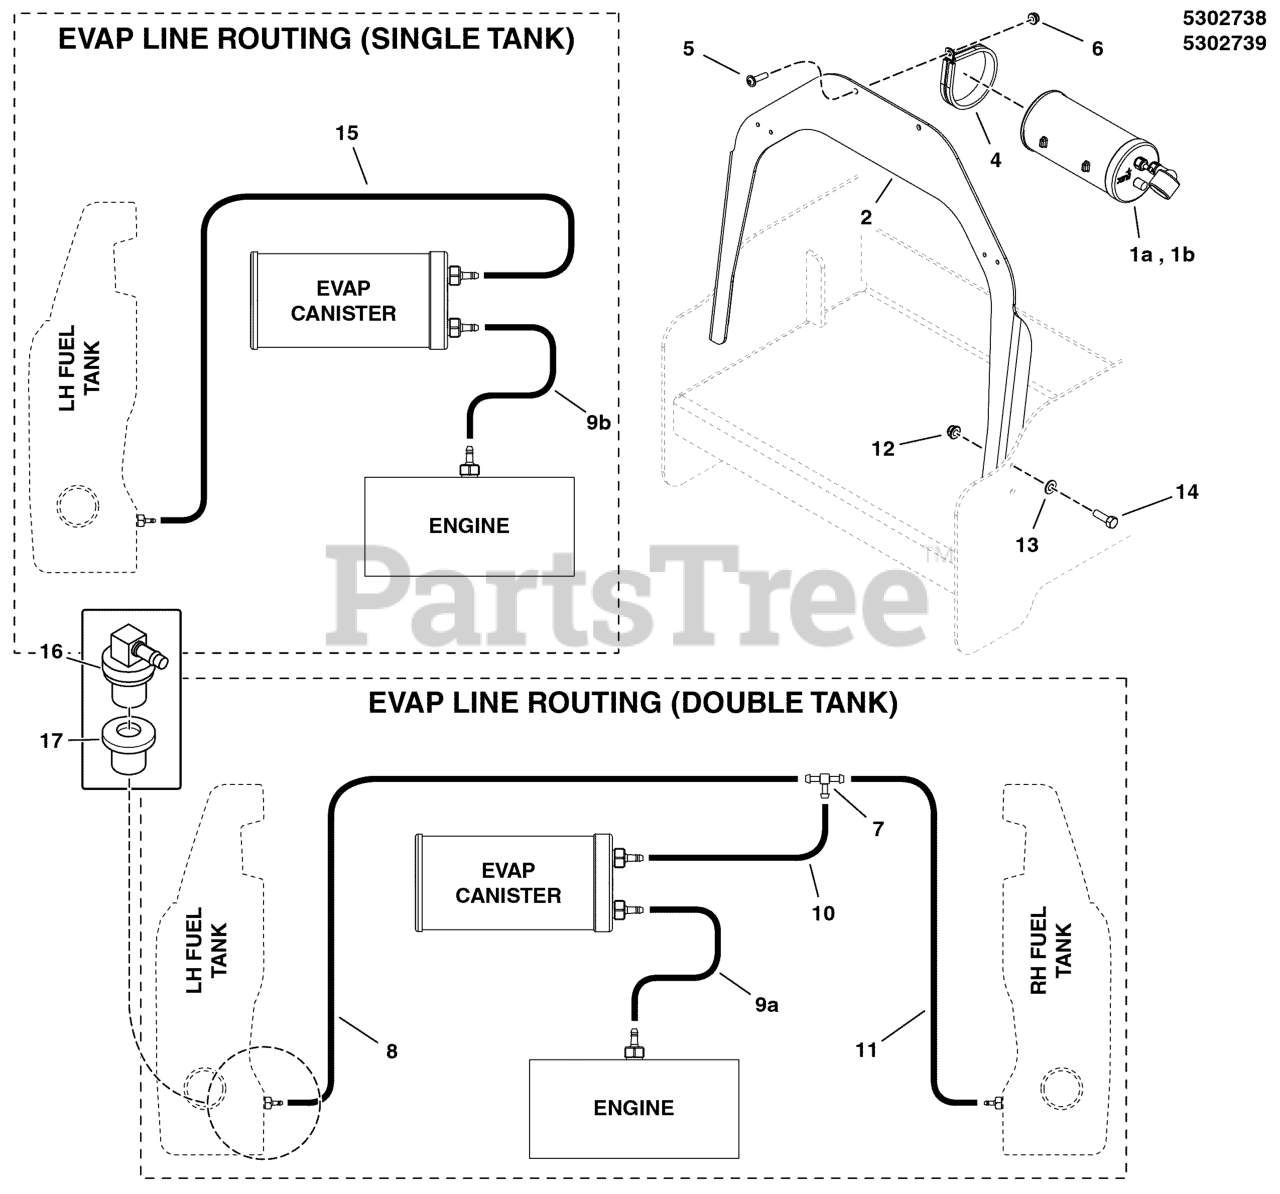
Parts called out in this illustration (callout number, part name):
2	BRACKET, CARB CANISTER, S50X - BLK
3	DECAL, EPA CERT, ZTRS
4	CLAMP, 3" ID, CUSHIONED, STAINLESS
6	NUT, 1/4-20 HEX NYLOCK FLANGE
7	FITTING, 3/16" TEE, BARB TYPE, HDPE
8	HOSE, VAPOR, 5MM ID, 39.00 LG
10	HOSE, VAPOR, 5MM ID, 5.00 LG
11	HOSE, VAPOR, 5MM ID, 15.00 LG
12	NUT, 5/16-18 HEX NYLOCK FLANGE
13	WASHER, 5/16" SAE
14	BOLT, 5/16-18 X 1 GD5 YZ
15	HOSE, VAPOR, 5MM ID, 29.50 LG
16	REMOTE VENT ASSEMBLY
17	GROMMET
